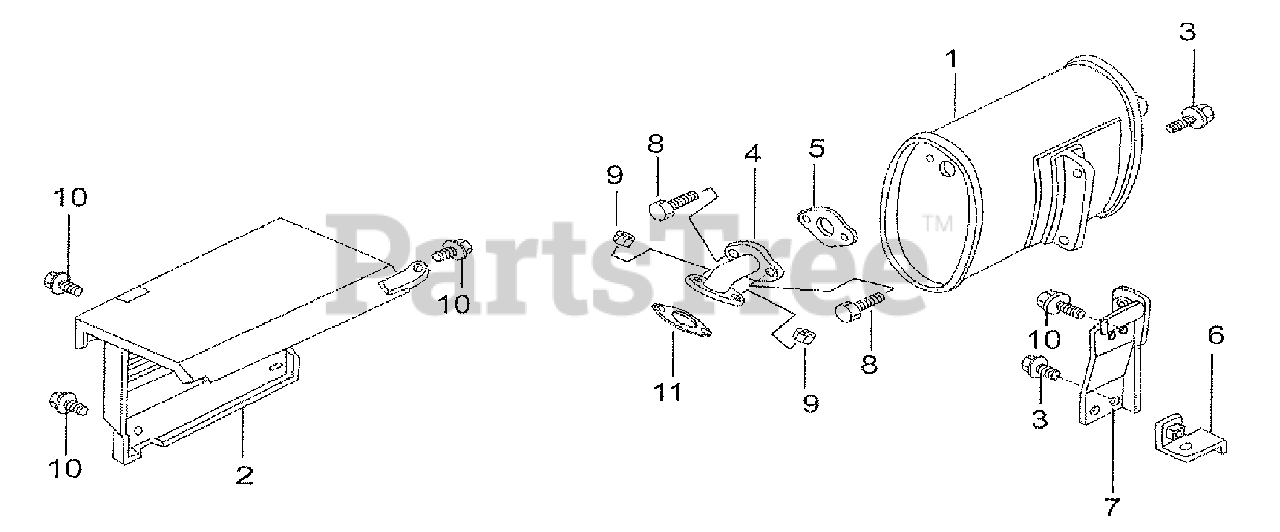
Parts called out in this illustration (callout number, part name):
1	MUFFLER COMP.
2	PROTR, OUT MUFFLER
3	BOLT, FLANGE, 8 X 16
4	PIPE COMP. EXH
5	GASKET, MUFFLER
6	SUPPORTING PLSTE
7	MUFFLER STAY
8	BOLT, FLANGE, 8 X 25
10	BOLT, FLANGE, 6 X 12
11	GASKET, MUFFLER
